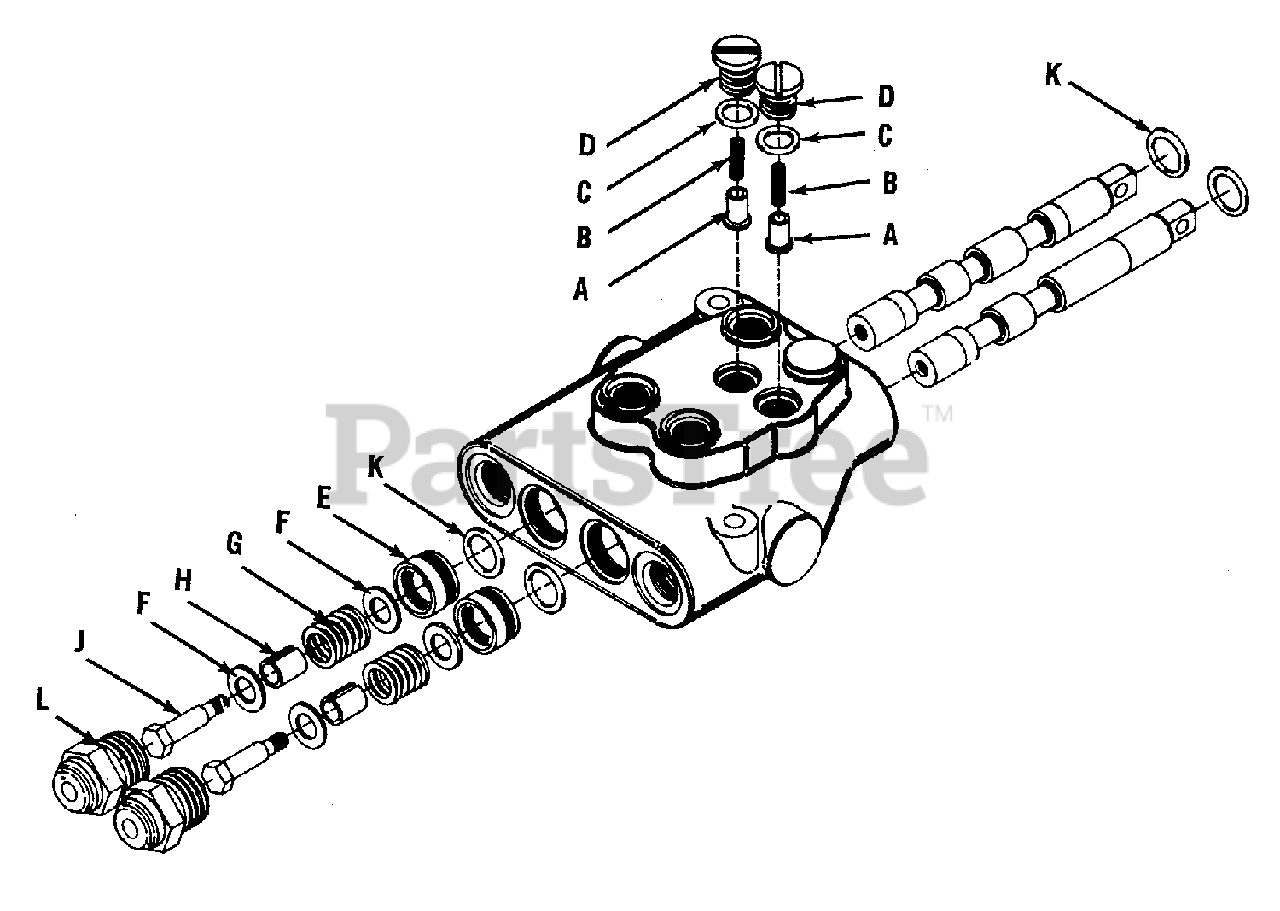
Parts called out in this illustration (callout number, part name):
A	PLUNGER, Lift Check
B	SPRING, Lift Check
C	RING, "O"
D	PLUG ASSEMBLY, Lift Check
F	WASHER, Steel
G	SPRING, Spool
H	SPACER, Spool
J	SCREW, Spool
K	RING, "O"
L	CAP ASSEMBLY
M	MAJOR SEAL REPAIR KIT
